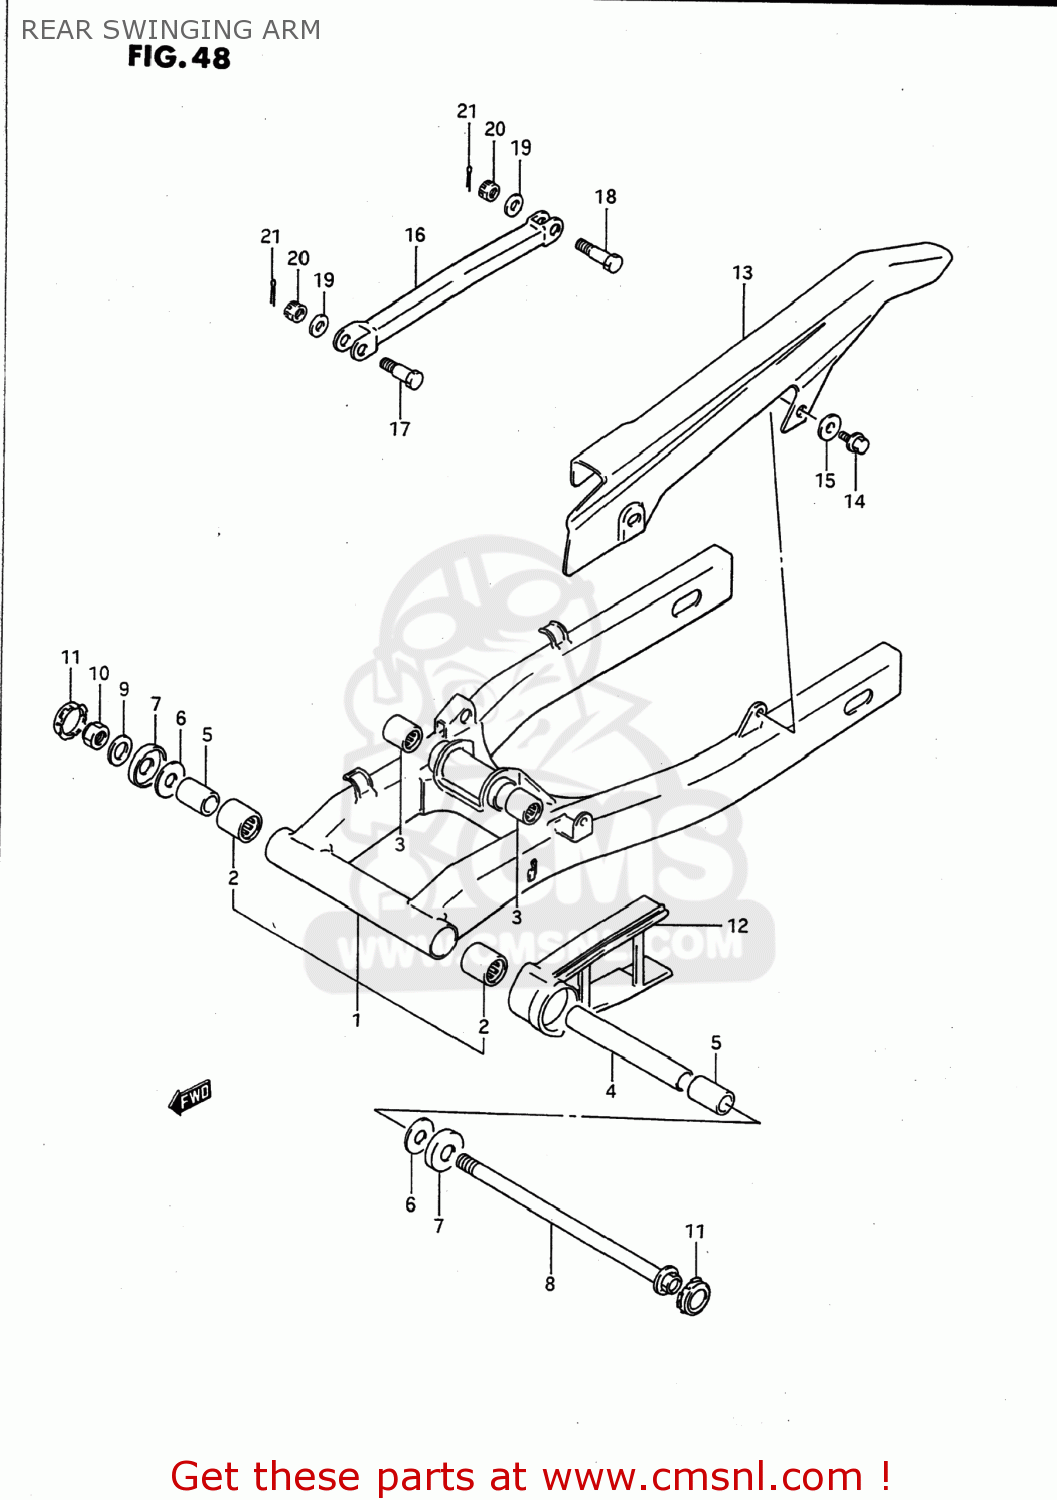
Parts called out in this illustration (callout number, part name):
1	SWING ARM ASSEMBLY,REAR
2	BEARING(22X29X30)
3	BEARING(17X24X25)
4	SPACER,RR SWGARM PIVOT CTR
5	SPACER,RR SWGARM PIVOT
6	WASHER(14.2X34X1)
7	CVR,RR SWGARM DUST SEAL(OD:40)
8	SHAFT,RR SWINGINGARM PIVOT
9	WASHER(14.5X29X2.3)
10	NUT
11	CAP,RR SWINGING ARM PIVOT
12	BUFFER,CHAIN TOUCH DEFENSE
13	CASE,CHAIN
14	BOLT
15	WASHER
16	TORQUELINK,RR
17	BOLT(10X41)
18	BOLT(10X35)
19	WASHER (10X18X3.2)
20	NUT
21	PIN 20X20
